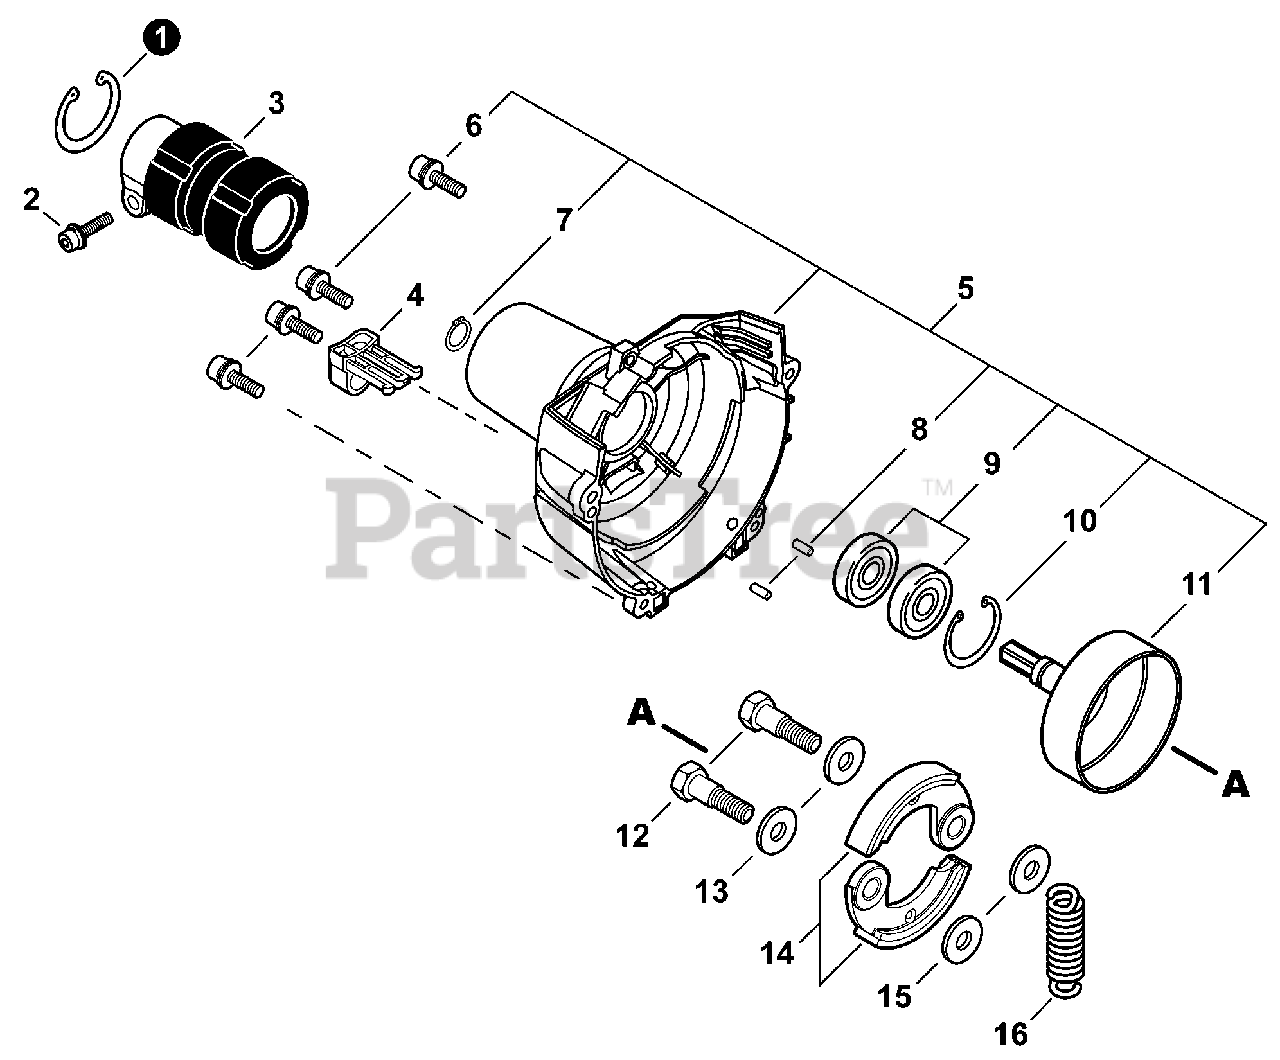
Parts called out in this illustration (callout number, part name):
1	RING, SNAP Ø42
2	BOLT 5×28
3	HOLDER, MAIN PIPE
4	CLIP
5	COVER ASSY, FAN
6	BOLT 4×16
7	RING, SNAP 12
8	PIN, LOCATING 4
9	BEARING, BALL 6001
10	RING, SNAP 28
11	DRUM, CLUTCH
12	BOLT, CLUTCH 8×7.9×M6
13	WASHER 8.5×16×0.5
14	SHOE, CLUTCH
15	WASHER 6.2×19×1.0
16	SPRING, CLUTCH
